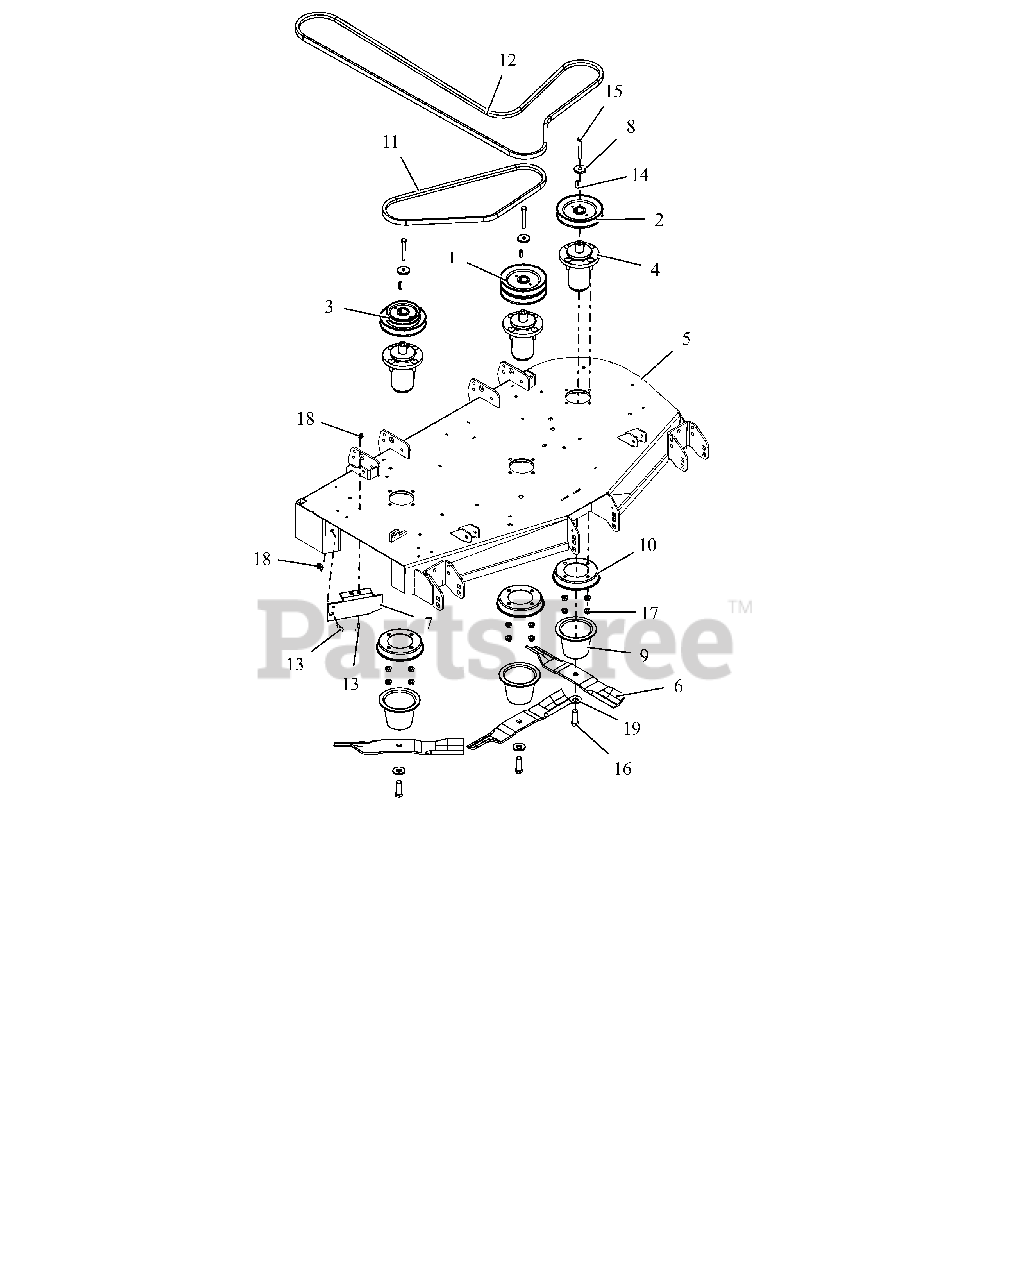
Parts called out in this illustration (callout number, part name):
1	PULLEY, DOUBLE-1"ID X 5.75"OD
2	PULLEY, V-1" ID X 5.75" OD
3	PULLEY, DBL-1"IDX5.75"&4.25"OD
4	ASM, MAINT FREE ALUM SPINDLE
5	DECK, PT48 W/SAFETY DECALS
6	BLADE, 16.19" MOWER (HI-LIFT)
7	44"-48" SIDE DISCH BAFFLE -RED
8	RETAINER, SHEAVE
9	GUARD, SPINDLE LOWER
10	GUARD, SPINDLE TOP
11	V-BELT, B-COGGED
12	V-BELT, B RAW EDGE EPDM
13	@BLT-RDHDSQNK .31-18X1.00 G5YZ
14	KEY, SQ .25X.25X1.00 RC 40-50
15	BLT, HEX .38-16X2.75 G8 ZCC
16	BLT, HEX .62-18X1.75 G8 ZCC
17	NUT-LK-CTR-FLG .375-16 GF ZCC
18	@NUT-LK-NYL-FLG .31-18 YWZC
19	WSHR-BLVL .669X1.535X.138
